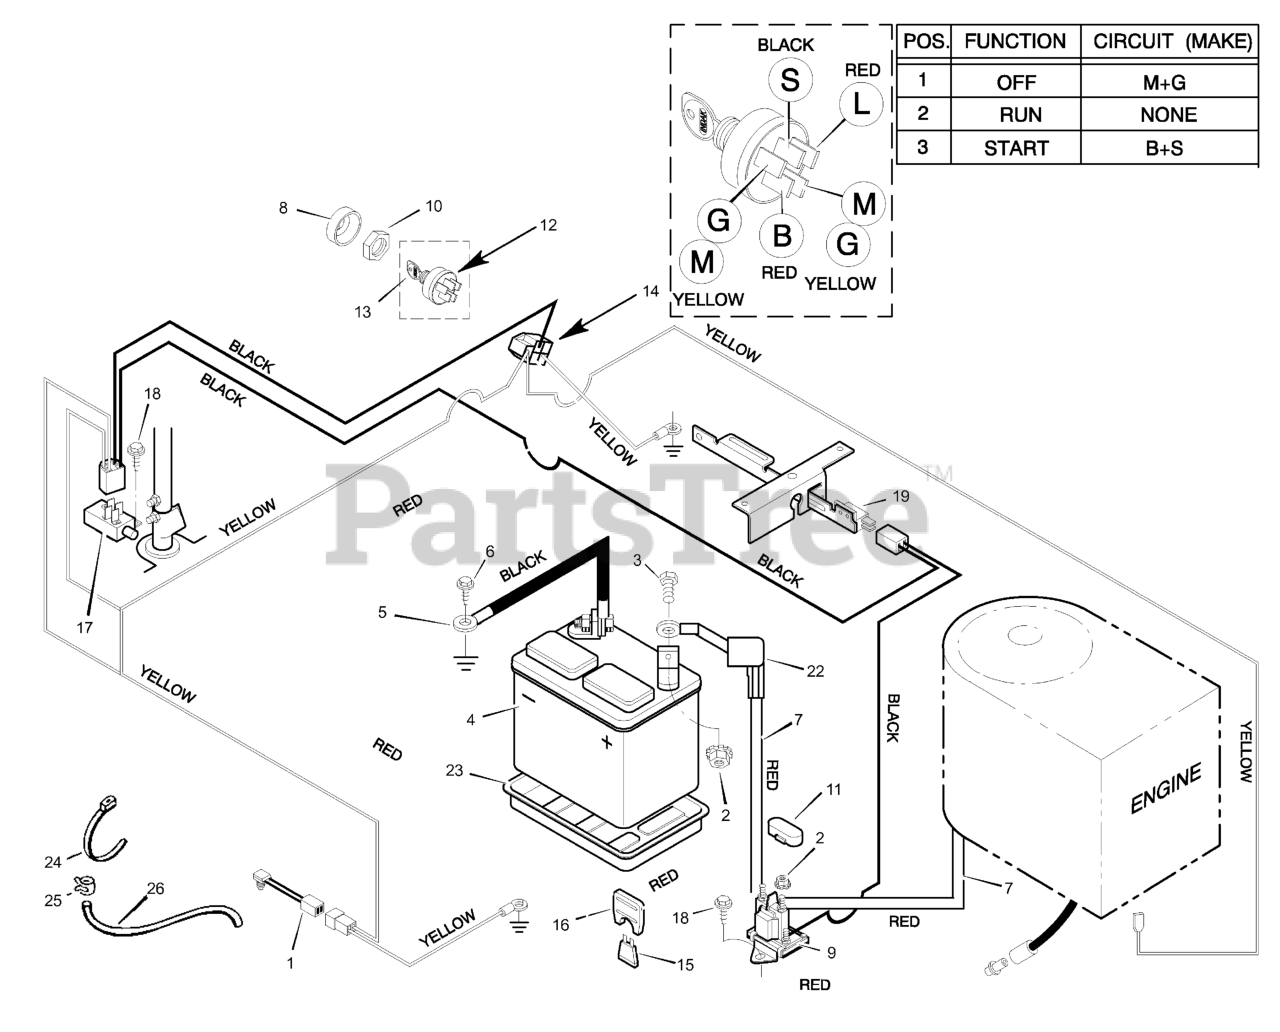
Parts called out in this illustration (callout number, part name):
1	Switch, Seat Sensor
2	Locknut
4	Battery
5	Cable, Battery Ground
7	Cable, Red Battery
8	Cap, Ignition
9	Solenoid
10	Nut, Hex
11	Cover, Solenoid
12	Switch, Ignition
13	Key, Ignition
14	Harness, Chassis Wire
16	Holder, Fuse
17	Switch, Limit
19	Switch, Limit
22	Cover, Terminal
23	Tray, Battery
24	Strap, Tie
26	Drain, Tube
